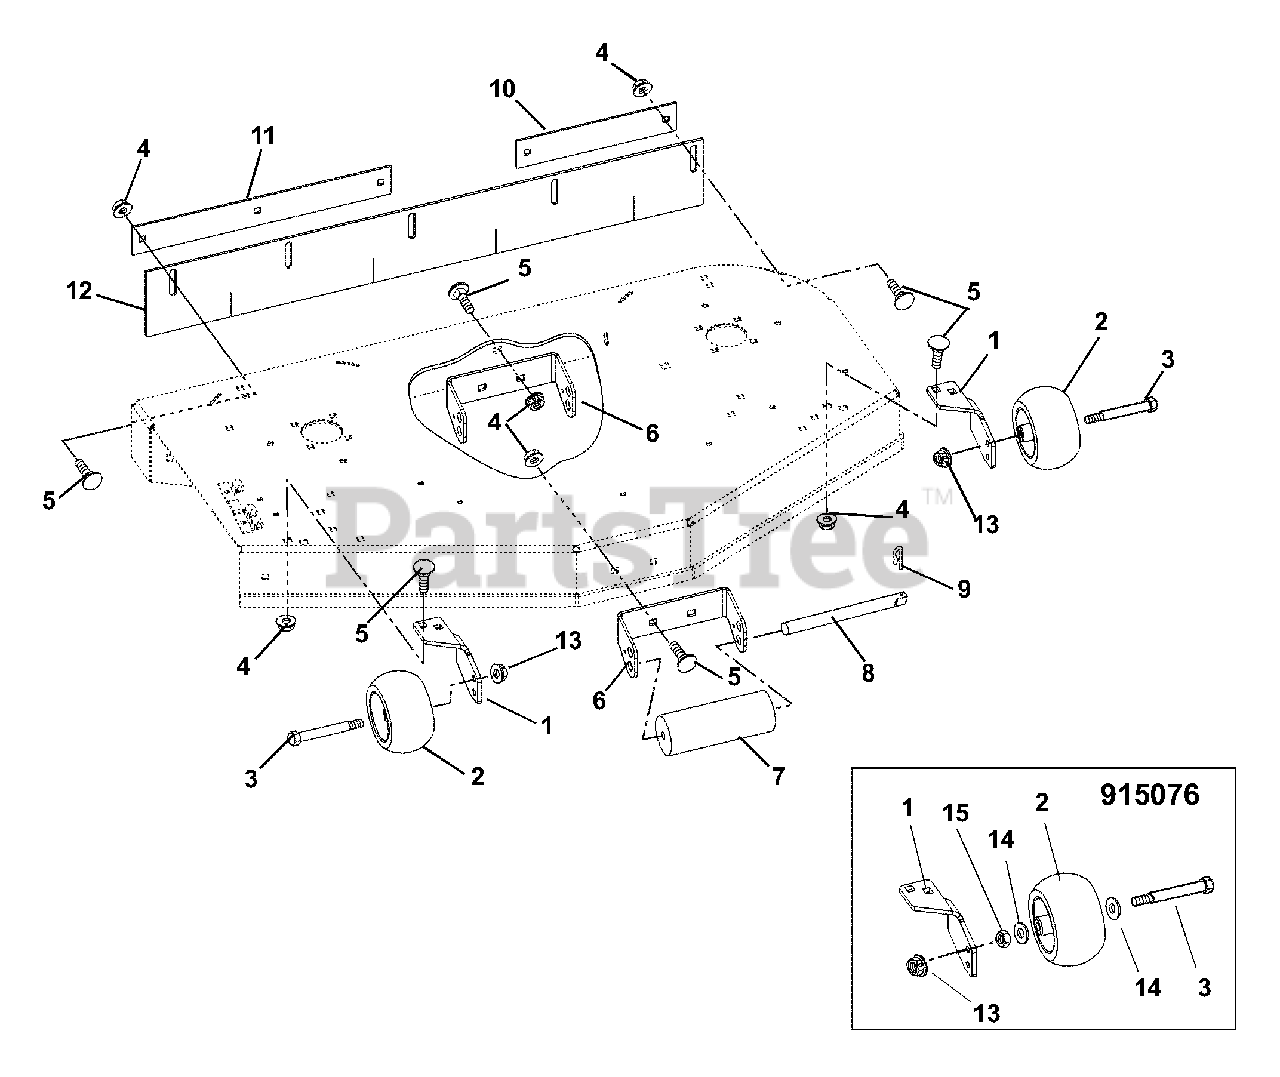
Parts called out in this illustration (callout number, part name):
1	Bracket, Anti-Scalp
2	Wheel 5 x 3
2	Roller
3	Bolt, Shoulder .38-16 x 2.50 Hex Washer Head Grade 5
3	Bolt, Shoulder .38-16 x 3.50 Hex Washer Head Grade 5
4	Nut .38-16 Flange Nyloc
5	Bolt-Round Head Square Neck .38-16 x 1.00 Grade 5
5	Bolt- Round Head Square Neck .38-16 x 1.00 Grade 5
6	Bracket, Roller Mount
7	Roller
8	Pin, Roller
9	Pin, Spring Clip
10	Bar, Left Hand Retainer Striper
11	Bar, Retaining Striper
12	Striper, Rubber-44"
12	Striper, Rubber-48"
12	Striper, Rubber-52"
12	Striper, Rubber-40"
13	Nut-Locking-Top-Flange .38-16
14	Washer, Flat Steel .406 x .812 x .065
15	Nut, Center Lock Jam .375-16
